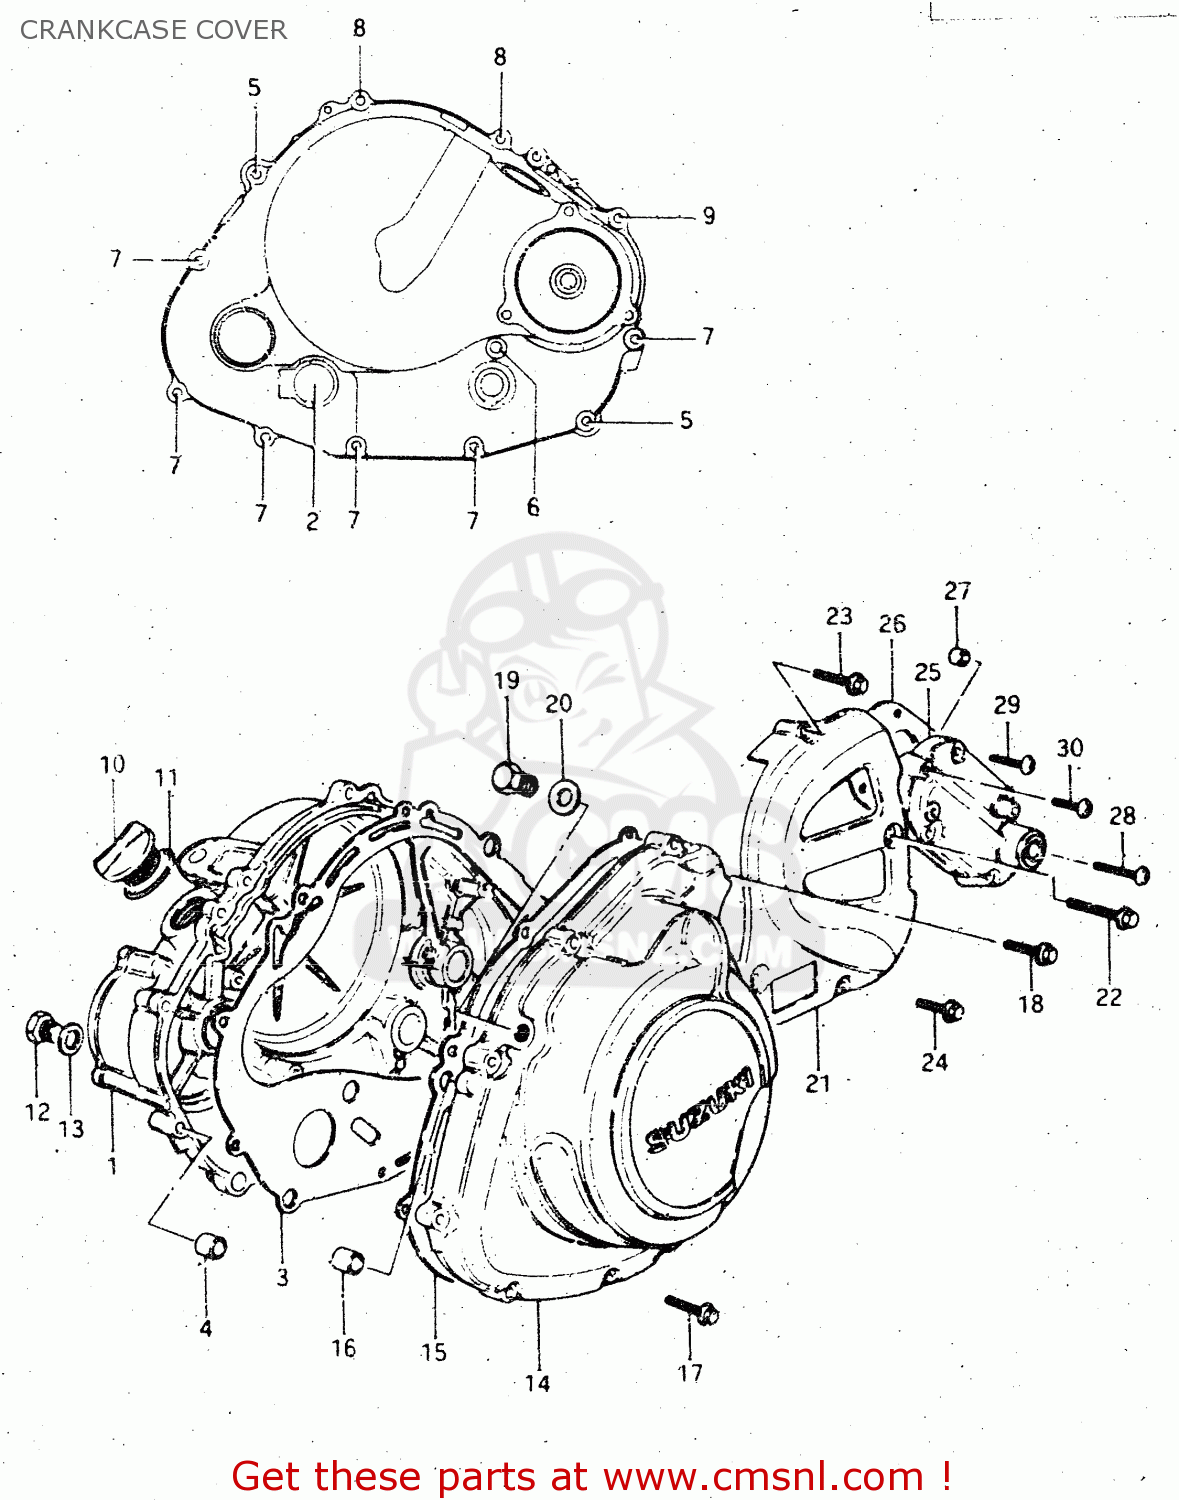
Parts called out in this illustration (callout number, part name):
1	COVER,CLUTCH
2	LENS,OIL LEVEL CHECK
3	GASKET,CLUTCH COVER (MCA)
4	PIN
5	BOLT 6X50
6	BOLT 6X40
7	BOLT 6X35
8	BOLT 6X25
9	SCREW(6X25)
10	CAP
11	O RING(D:2.2,ID:32)
12	PLUG(14X12)
13	GASKET(14X19.2X2) (NAS)
14	COVER,MAGNETO
15	GASKET,MAGNETO COVER (MCA)
16	PIN
17	BOLT 6X30
18	BOLT 6X25
19	PLUG(12X9)
20	GASKET(12.1X16.2X3.7) (NAS)
21	COVER,ENGINE SPROCKET
22	BOLT
23	BOLT 6X30
24	BOLT 6X20
25	COVER,GEAR SHIFT
26	CUSHION,ENGINE SPROCKET
27	PIN
28	SCREW (6X35)
29	SCREW 6X30
30	SCREW
